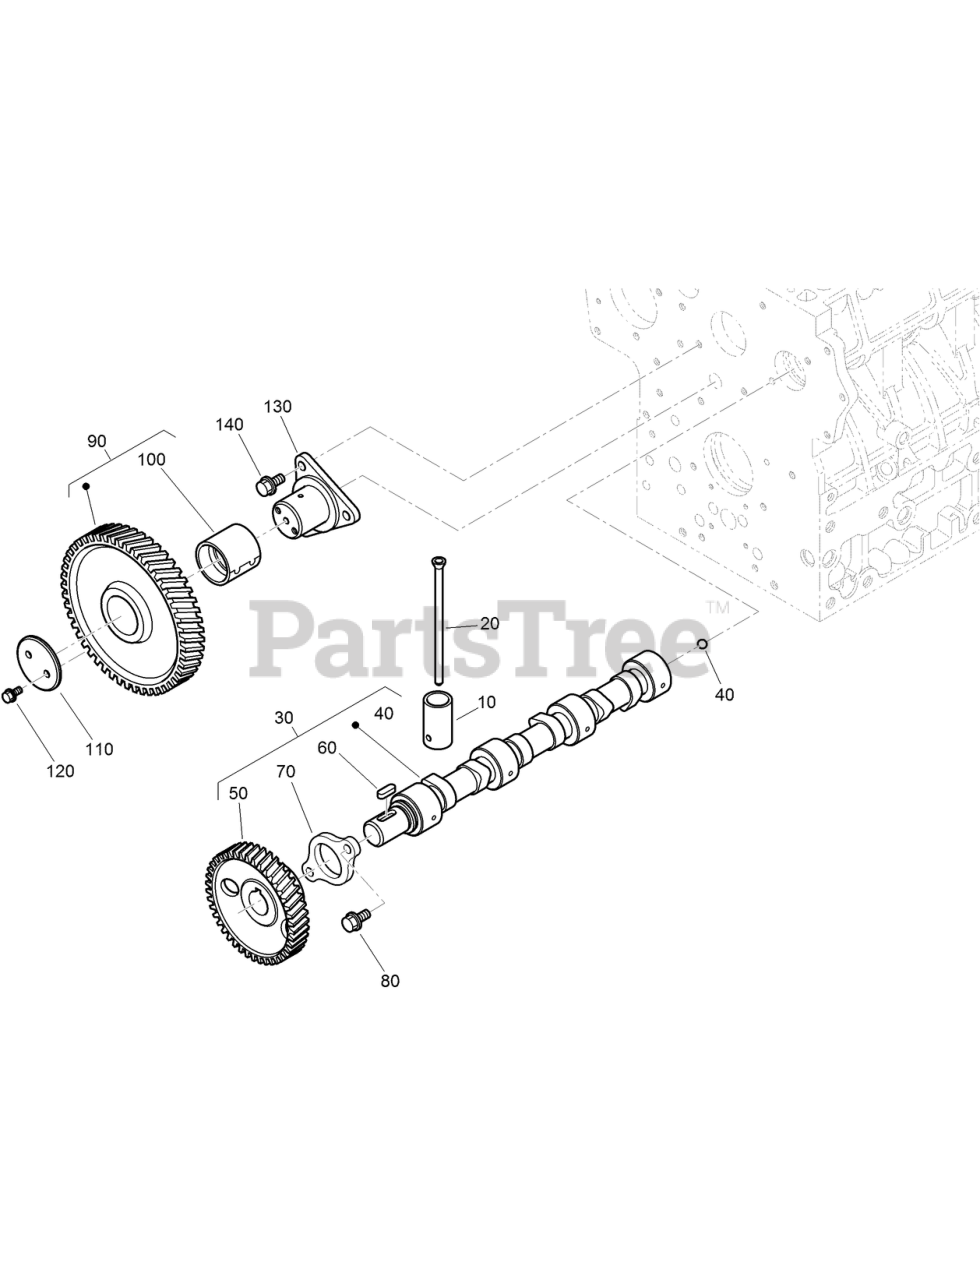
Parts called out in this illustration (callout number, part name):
10	NARROW BUCKET ASM
20	ROD-PUSH
30	CAMSHAFT ASM
50	GEAR-CAMSHAFT
60	KEY-FEATHER
70	STOPPER-CAMSHAFT
80	BOLT-FLANGE
90	GEAR-IDLE
100	BUSHING-GEAR, IDLE
110	COLLAR-GEAR, IDLE
120	NARROW BUCKET ASM
130	SHAFT-GEAR, IDLE
140	BOLT-FLANGE
